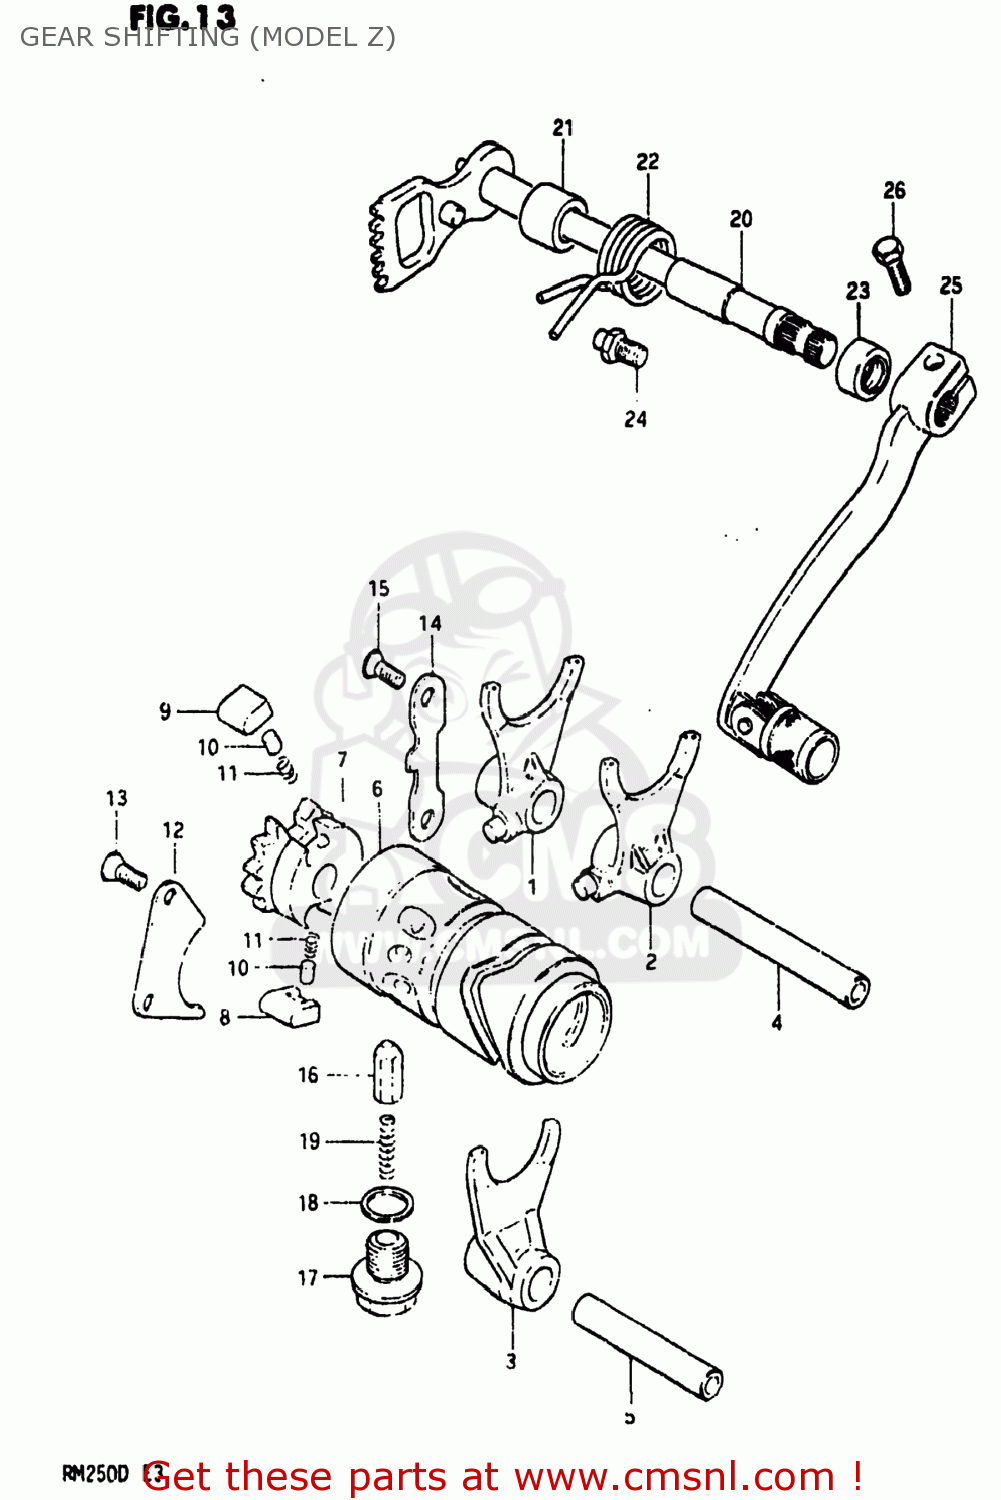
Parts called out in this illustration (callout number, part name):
1	FORK,GEAR SHIFT NO.1
2	FORK,GEAR SHIFT NO.2
3	FORK,GEAR SHIFT NO.3
4	SHAFT,GEAR SHIFT FORK
5	SHAFT,GEAR SHIFT FORK
6	CAM,GEAR SHIFT
7	RETAINER,GEAR SHIFT CAM
8	PAWL,GEAR SHIFT NO.1
9	PAWL,GEAR SHIFT NO.2
10	PIN(5X8)
11	SPRING
12	LIFTER,GEAR SHIFT PAWL
13	SCREW
14	GUIDE,GEAR SHIFT CAM
15	SCREW
16	STOPPER,GEAR SHIFTING
17	BOLT,GEAR SHAFT CAM STOPPER
18	GASKET(14X19.2X2) (NAS)
19	SPRING
20	SHAFT,GEAR SHIFT
21	SPACER(12X20X15.3)
22	SPRING
23	OIL SEAL
24	STOPPER,GEAR SHIFT CAM
25	LEVER ASSEMBLY,GEAR SHIFTING
26	BOLT
